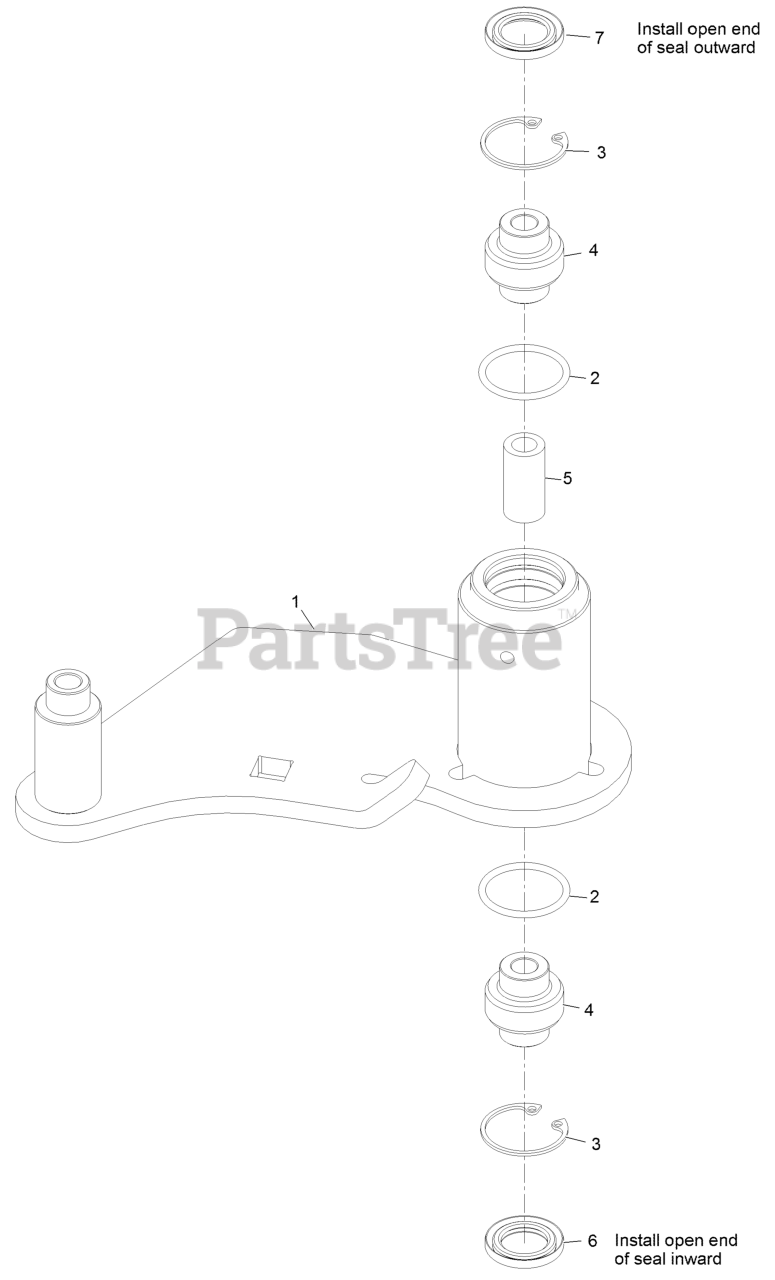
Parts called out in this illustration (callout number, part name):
1	Deck Idler [red]
3	RING-SNAP
4	BEARING-SPHERICAL
6	SEAL-LIP, DOUBLE
7	SEAL-LIP, SINGLE
